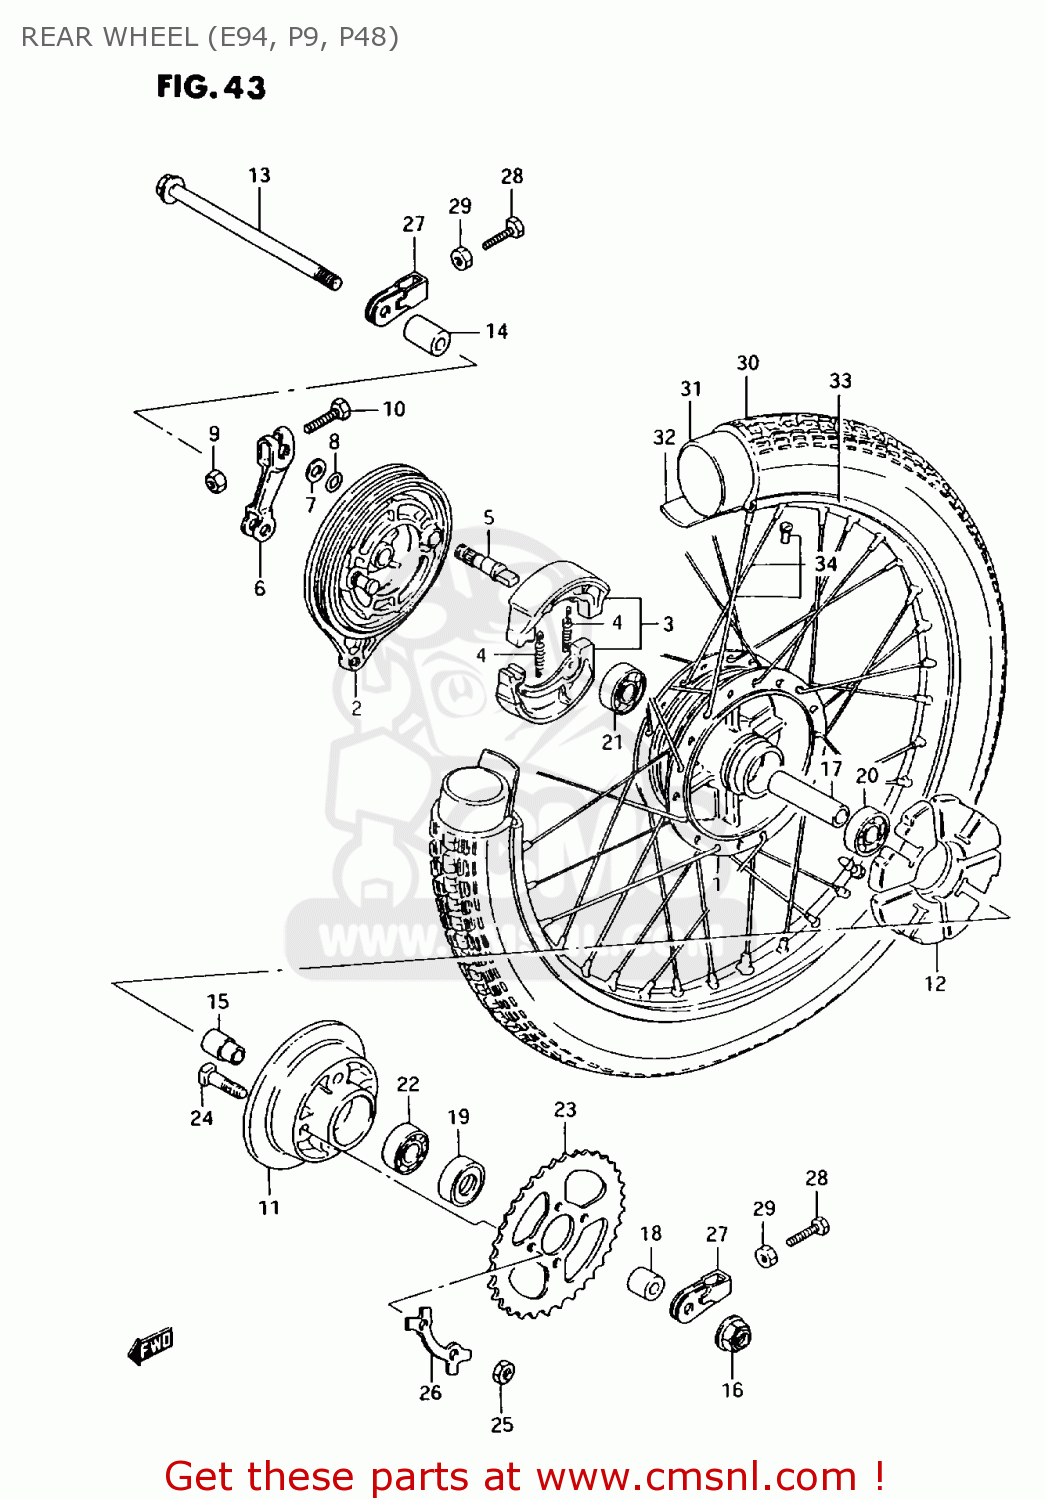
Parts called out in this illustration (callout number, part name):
1	HUB,RR WHEEL
2	PANEL,RR BRAKE ANCHOR
3	SHOE & SPRING SET,BRAKE (NAS)
4	SPRING
5	CAM,BRAKE
6	LEVER,RR BRAKE CAM
7	WASHER (14.5X22X1.6)
8	O-RING (D:2.4 ID:13.8)
9	NUT
10	BOLT(6X32)
11	DRUM,RR SPROCKET MOUNTING
12	ABSORBER,RR WHEEL HUB SHOCK
13	AXLE,RR
14	SPACER(12.2X22X39)
15	RETAINER,RR SPROCKET DRUM
16	NUT 12MM
17	SPACER (12.6X19X58)
18	SPACER(12X25X25)
19	SEAL,OIL(25X40X6)
20	BEARING
21	BEARING
22	BEARING
23	SPROCKET,RR(NT:44)
24	BOLT(8X33.5)
25	NUT
26	WASHER
27	ADJUSTER,CHAIN
28	BOLT(8X50)
29	NUT
30	TIRE,RR(2.75-18 42P)
31	TUBE,INNER
32	PROTECTOR,INNER TUBE
33	RIM,WHEEL(1.40X18)
34	SPOKE SET,RR
